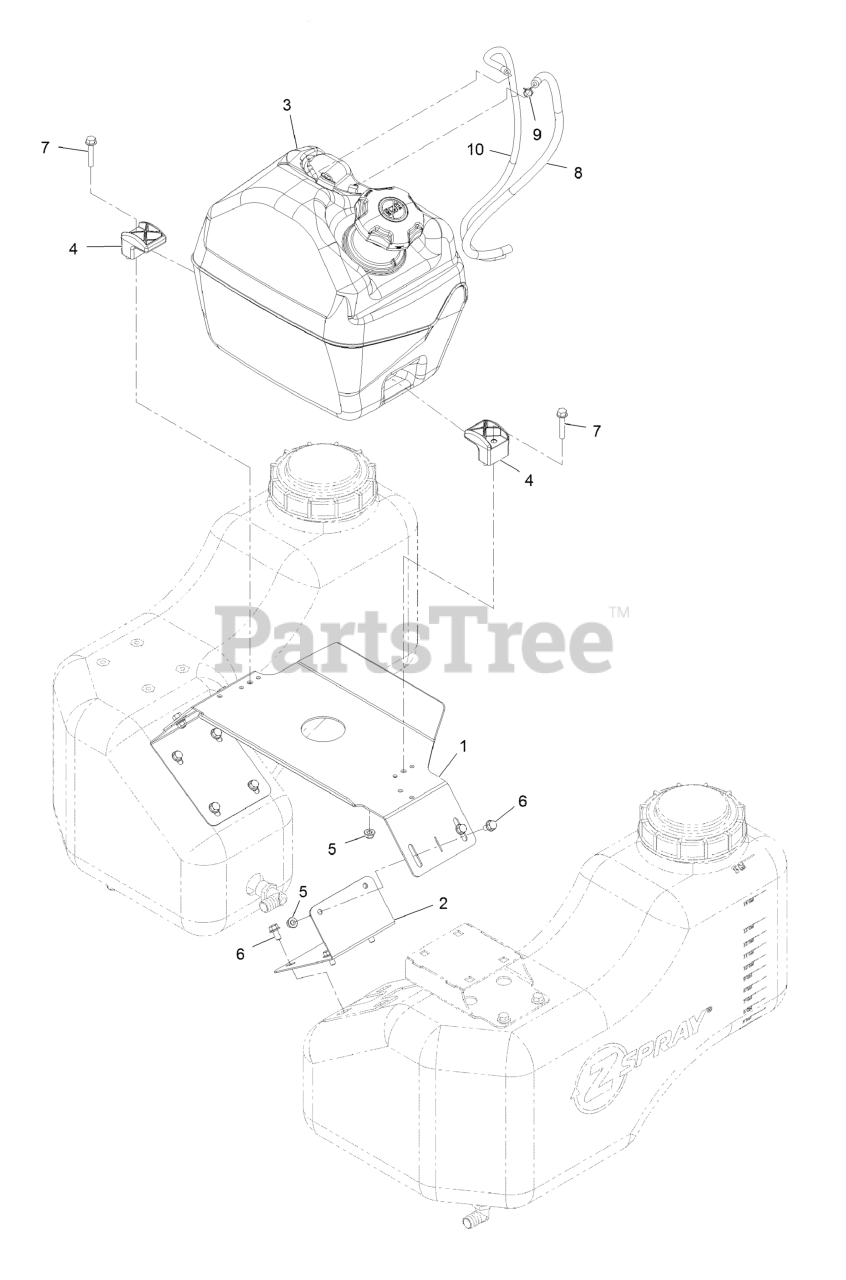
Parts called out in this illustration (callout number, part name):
1	Support-Fuel Tank
2	BRACKET-SUPPORT, GAS TANK
3	Fuel Tank ASM, 5 Gal
5	Nut-Hex Flange
6	Screw-HHF
7	Screw-HHF
8	HOSE-FUEL
9	CLAMP-HOSE
10	HOSE-FUEL
